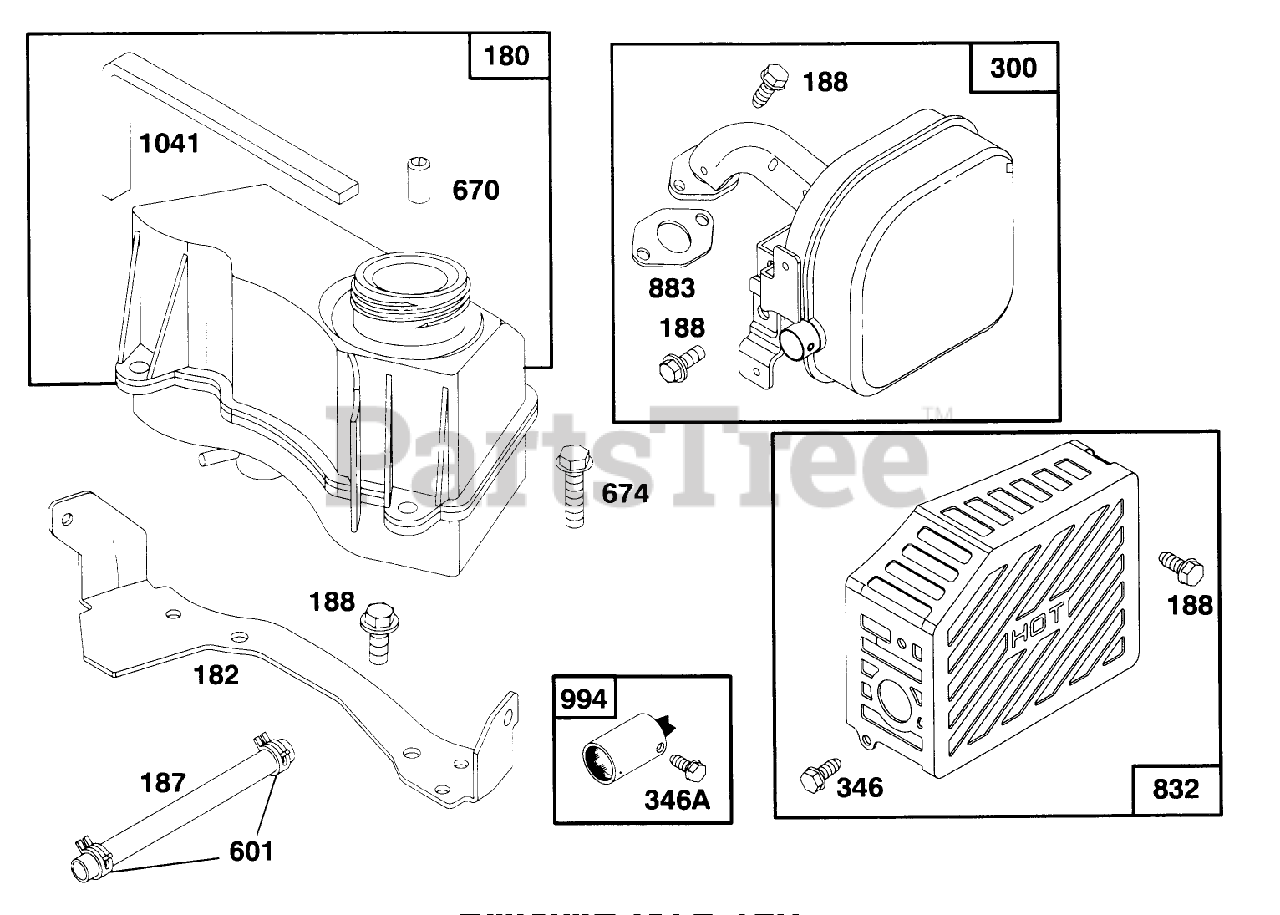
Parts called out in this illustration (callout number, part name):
180	TANK ASSY - FUEL
300	MUFFLER - EXHAUST
601	CLAMP - CL PIPE
670	SPACER
674	SCREW - HEX HEAD
